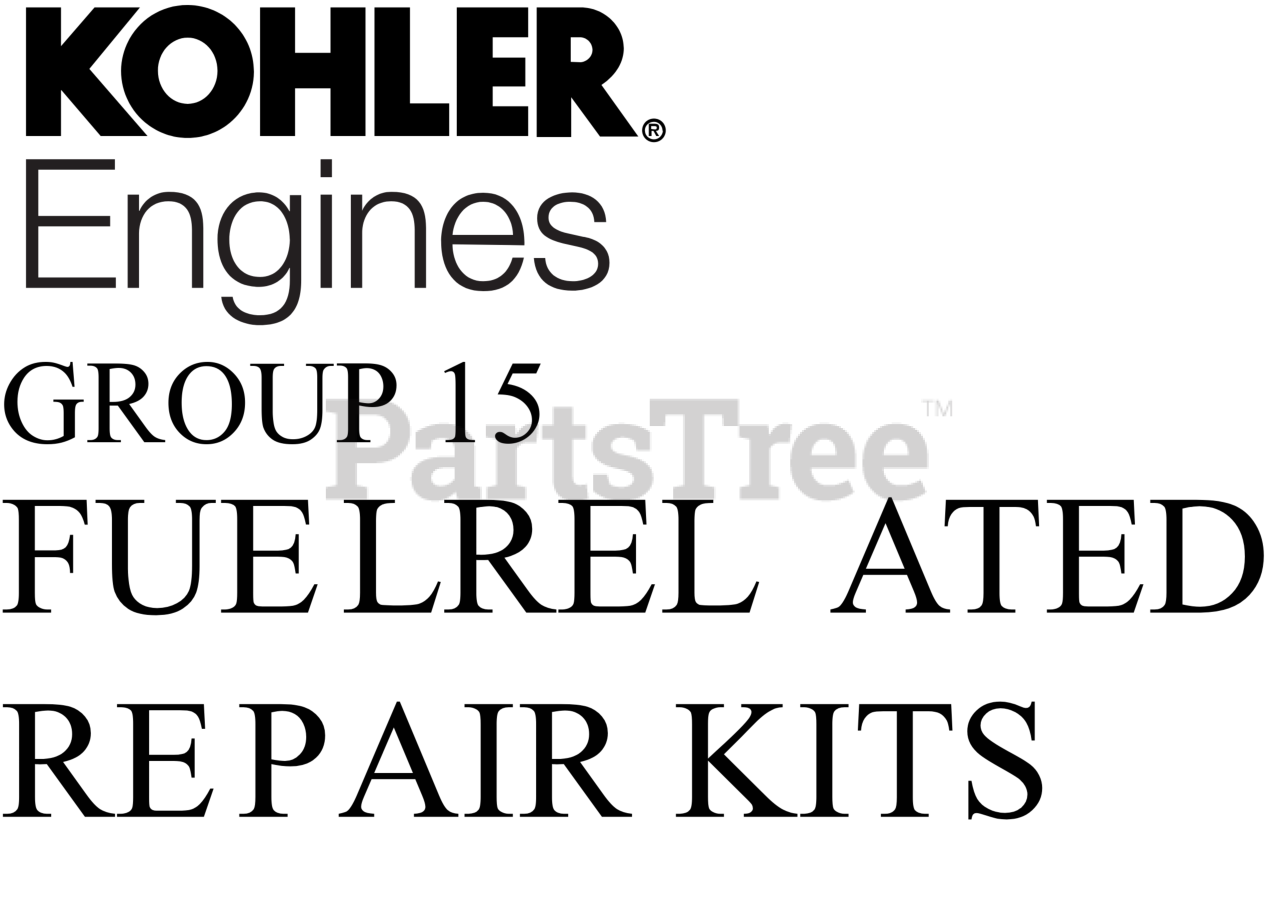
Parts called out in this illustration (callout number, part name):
NI	KIT, OVERHAUL NIKKI G-TYPE TWIN
NI	KIT, BOWL WITH O-RINGS NIKKI G-TYPE TWIN
NI	KIT, FLOAT AND NEEDLE NIKKI G-TYPE TWIN
NI	KIT,THROTTLE SHAFT(22MM)NIKKI G-TYPETWIN
NI	KIT,CHOKE REP(SMART/E-CHOKE)-DISC.
NI	KIT,HIGH ALT(22MM) NIKKI-USE 16 755 19-S
NI	KIT, SOLENOID (NIKKI)
